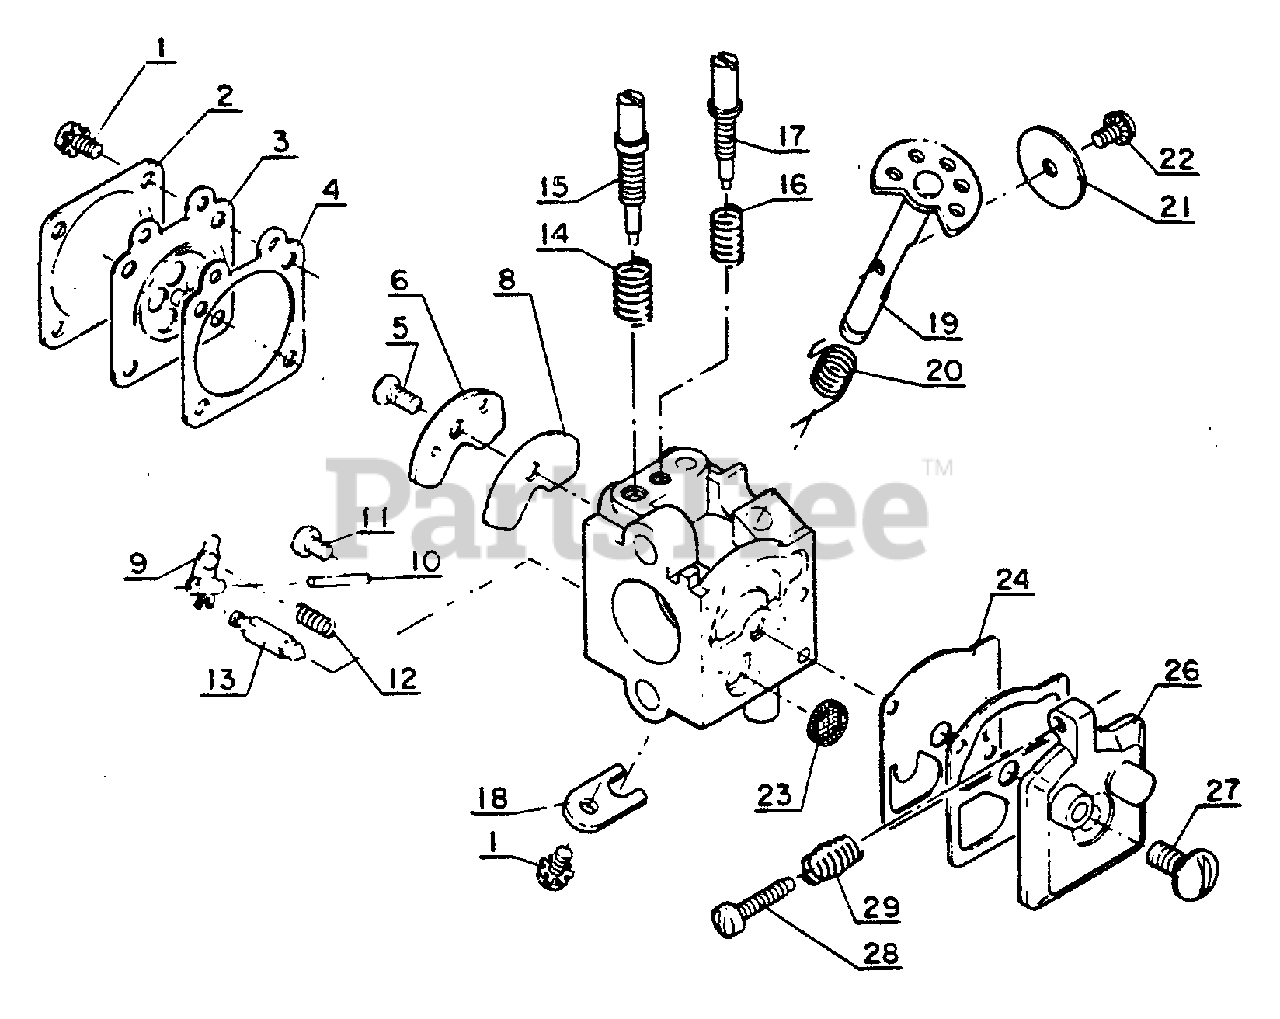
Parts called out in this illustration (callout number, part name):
2	COVER, METERING DIAPHRAGM
3	DIAPHRAGM, METERING
4	GASKET, METERING DIAPHRAGM
5	SCREW, CIRCUIT PLATE
6	PLATE, CIRCUIT
8	GASKET, CIRCUIT PLATE
9	LEVER, METERING
10	PIN, METERING LEVER
11	SCREW, METERING LEVER PIN
13	VALVE, INLET NEEDLE
14	SPRING, NEEDLE
15	NEEDLE, HIGH SPEED
16	SPRING, NEEDLE
17	NEEDLE, IDLE
18	CLIP, THROTTLE SHAFT
19	SHAFT, THROTTLE
20	SPRING, THROTTLE RETURN
21	VALVE, THROTTLE
23	STRAINER
24	DIAPHRAGM, FUEL PUMP
25	GASKET, FUEL PUMP
26	COVER, PUMP
28	SCREW, IDLE ADJUST
29	SPRING, IDLE ADJUST
